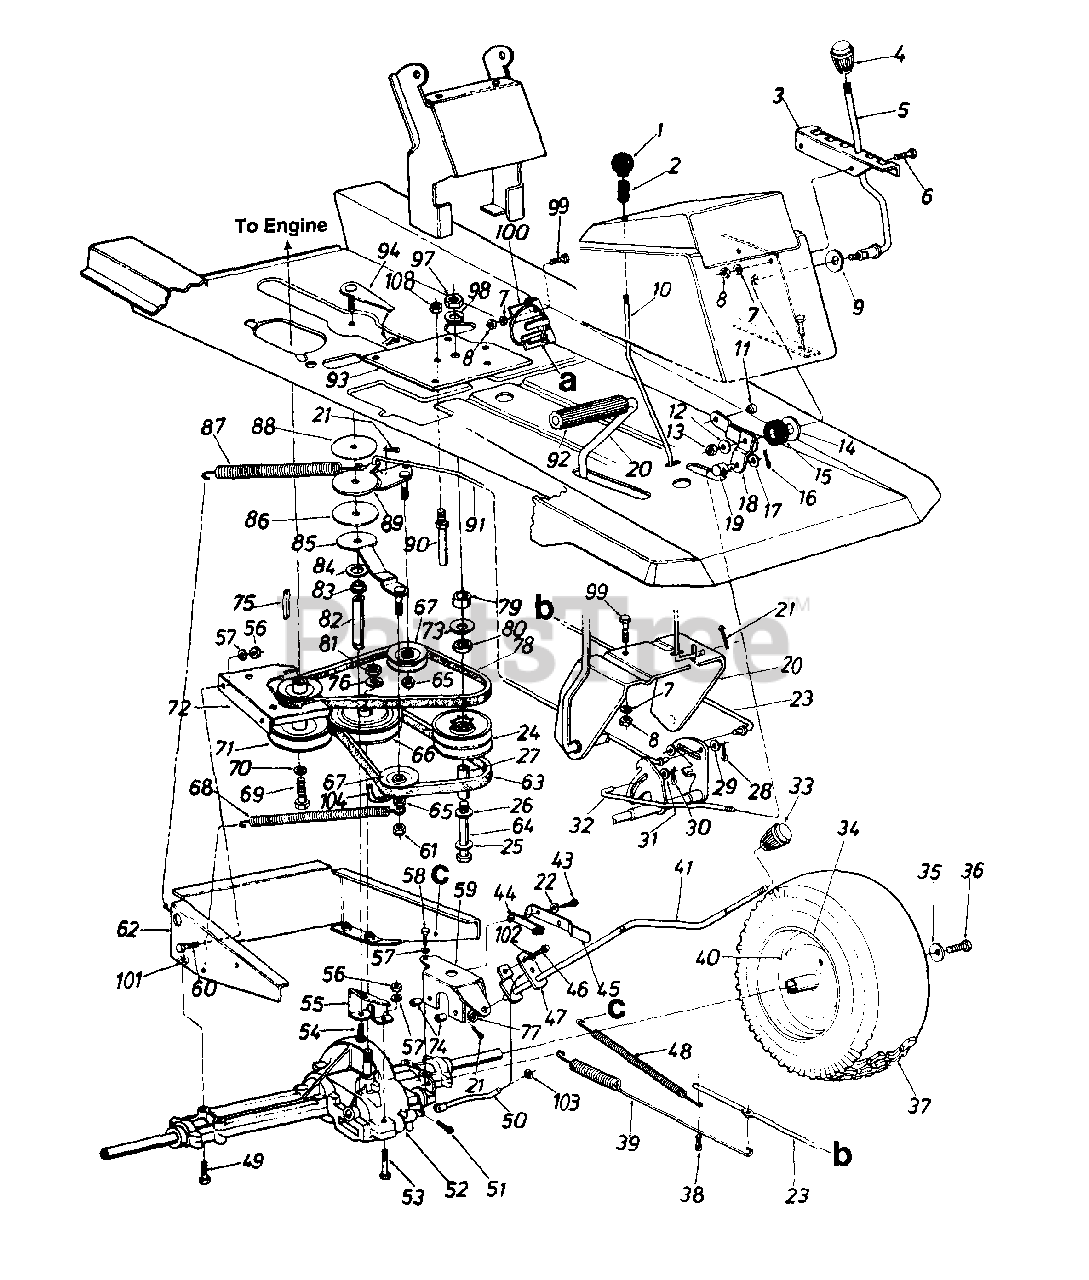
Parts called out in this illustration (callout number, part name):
1	Ball Knob 1/4-20 Thd. 1.25"
2	Compression Spring
5	Speed Control Lever
6	Truss Mach. Scr. 5/16-18 x .75" Lg.
7	L - Wash. 5/16" I.D.
8	Hex Nut 5/16-18 Thd.
9	Bell - Wash. .345" I.D. x .88"
10	Brake Locking Rod
11	Cap
12	Bell - Wash. .345" I.D. x .08"
13	Hex Cent. L - Nut 5/16-18 Thd.
14	Fl - Wash. .50" I.D. x 1.5" O.D.
15	Rubber Washer
16	Intern. Cotter Pin 1/2" Dia.
17	Fl - Wash. .34" I.D. x .68" O.D.
18	Speed Control Lever Brkt. Ass'y.
19	Ferrule - Engagement
20	Clutch/Brake Pedal Ass'y.
21	Cotter Pin 3/32" Dia. x .75"
22	Plastic Washer
23	Brake Rod
24	Variable Speed Pulley Ass'y.
25	Fl - Wash. .4" I.D. x 1.25" O.D.
26	Thrust Brg. 1.25" O.D. x .56" I.D.
27	Spacer Sleeve 2.71"
28	Cotter Pin 1/8" Dia. x 1.25"
29	Fl - Wash. .34" I.D. x .60" O.D.
30	Intern. Cot - Pin 5/16" Dia.
31	Fl - Wash. .34" I.D. x .60" O.D.
32	Speed Control Rod
33	Shift Knob
35	Bell - Wash. .345" I.D. x .88"
36	Hex L - Bolt 5/16-24 x .75" Lg.
38	Cotter Pin 1/8" Dia. x 1.25"
39	Extension Spring 17.0" Lg.
40	Air Valve
44	Insulator Nut
45	Spring Switch
46	Hex Bolt 1/4-20 x .50" Lg.
47	Shift Lever Adjusting Link
48	Ext. Spring 81/4" Lg.
49	Hex Bolt 5/16-18 x 2.5" Lg.
50	Shift Rod
51	Intern. Cotter Pin
52	Transaxle
53	Hex Bolt 1/4-20 x 1.75" Lg.
54	Hex Bolt 3/8-24 x .75" Lg.
57	L - Wash. 1/4" I.D.
58	Self - Tap Mach. Scr. Type "C" 1/4-20 x 1.37" Lg.
59	Shift Lever Support Brkt.
60	Hex Bolt 1/4-20 x 1.00" Lg.
61	Hex L - Nut 3/8-24 Thd.
64	Hex Bolt 3/8-16 x 4.5" Lg.
65	Hex Ins. L - Nut 3/8-24 Thd.
66	V - Pulley
67	V - Belt Idler .38" I.D. x 3.06"
68	Ext. Spring .50" O.D. x 6.37"
69	Hex Bolt 7/16-20 x 1.00" Lg.
70	L - Wash. 7/16" I.D.
71	Engine Pulley
72	Upper Eng. Belt Guard
73	Bell - Wash. .4" I.D. x 1.12" O.D.
74	Spacer .256" I.D. x .50" O.D.
75	Sq. - Key 1/4" x 2.00" Lg.
76	Bell - Wash..567" I.D. x 1.125"
77	Fl - Wash..469" I.D. x .88" O.D.
78	V - Belt
79	Spacer 1.00" x .380" O.D.
80	Thrust Wash. .56" I.D. x 1.25" O.D.
81	Hex Jam Nut 9/16-18 Thd.
82	Torque Rod
83	Flange Bearing .378
84	Fl - Wash. .640" I.D. x 1.24"
85	Idler Bracket Ass'y.
86	Thrust Wash. .635" I.D.
87	Extension Spring 7.58" Lg.
88	Thrust Wash. .385" I.D.
89	Idler Bracket Ass'y. For Clutch
90	Belt Guard Pin 3/8-16 x 2.75" Lg.
91	Clutch Rod
92	Foot Pad
98	L - Wash. 3/8 Heavy Duty
99	Hex Bolt 5/16-18 x .75" Lg.
100	Speed Control Rod Brkt.
101	Hex Sems Nut 5/16-18 Thd.
102	Bell - Wash. .265" I.D. x .75" O.D.
103	Push On Retaining Ring
104	Belt Guard
107	Comp. Spring Clip
108	Hex Top L - Jam Nut 3/8-16 Thd.
